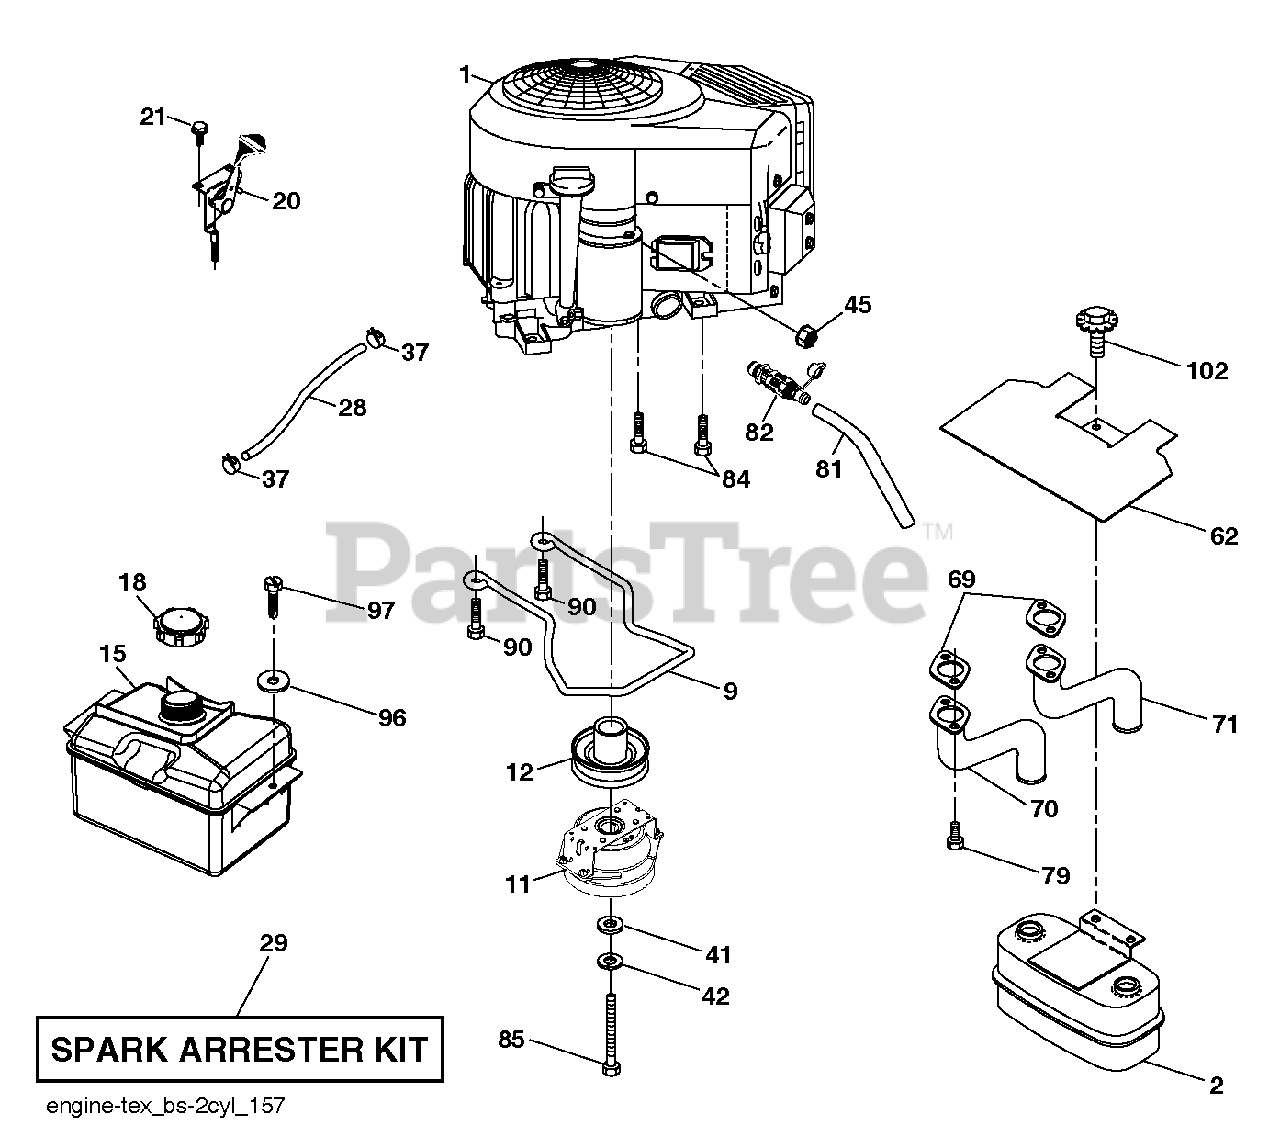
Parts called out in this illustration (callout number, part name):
2	MUFFLER.ASM.TWN.EXTNDED.DFLCTR
9	KEEPER.BELT.ENG.4.25"2.BLT.431
11	CLUTCH.OGURA.5.0PD.GT1.5A-EH07
12	PULLEY.ENGINE.TUFFTORQ
15	TANK.ASSEMBL.2.5GAL.NON-EPA
18	CAP ASM.FUEL.2.25"FR.
20	THROTTLE.COBRA.38"READSTART.BK
21	SCREW.#10 X 0.750.BOS
28	LINE.FUEL.20
29	KIT.SPARK ARRESTOR 794945 B&S
37	HOSE CLAMP
42	WASHER 7/16 LOCK
45	NUT
62	SHIELD.HEAT.MUFFLER
69	GASKET.MUFFLER
70	EXHAUST.TUBE.LH.BS/TWIN
71	EXHAUST.TUBE.RH.B&S.TWIN.INTEK
79	SCREW.SOCKET.HEAD.5/16-18
81	TUBE, DRAIN OIL ASM.
82	VALUE.OIL.DRAIN
84	SCREW.3/8-16
85	BOLT.HEX.7/16-20X3.75.GR5.RED
90	SCREW 3/8-16X1
97	SCREW HEXWSHR 1/4-20X3/4
102	SCREW
